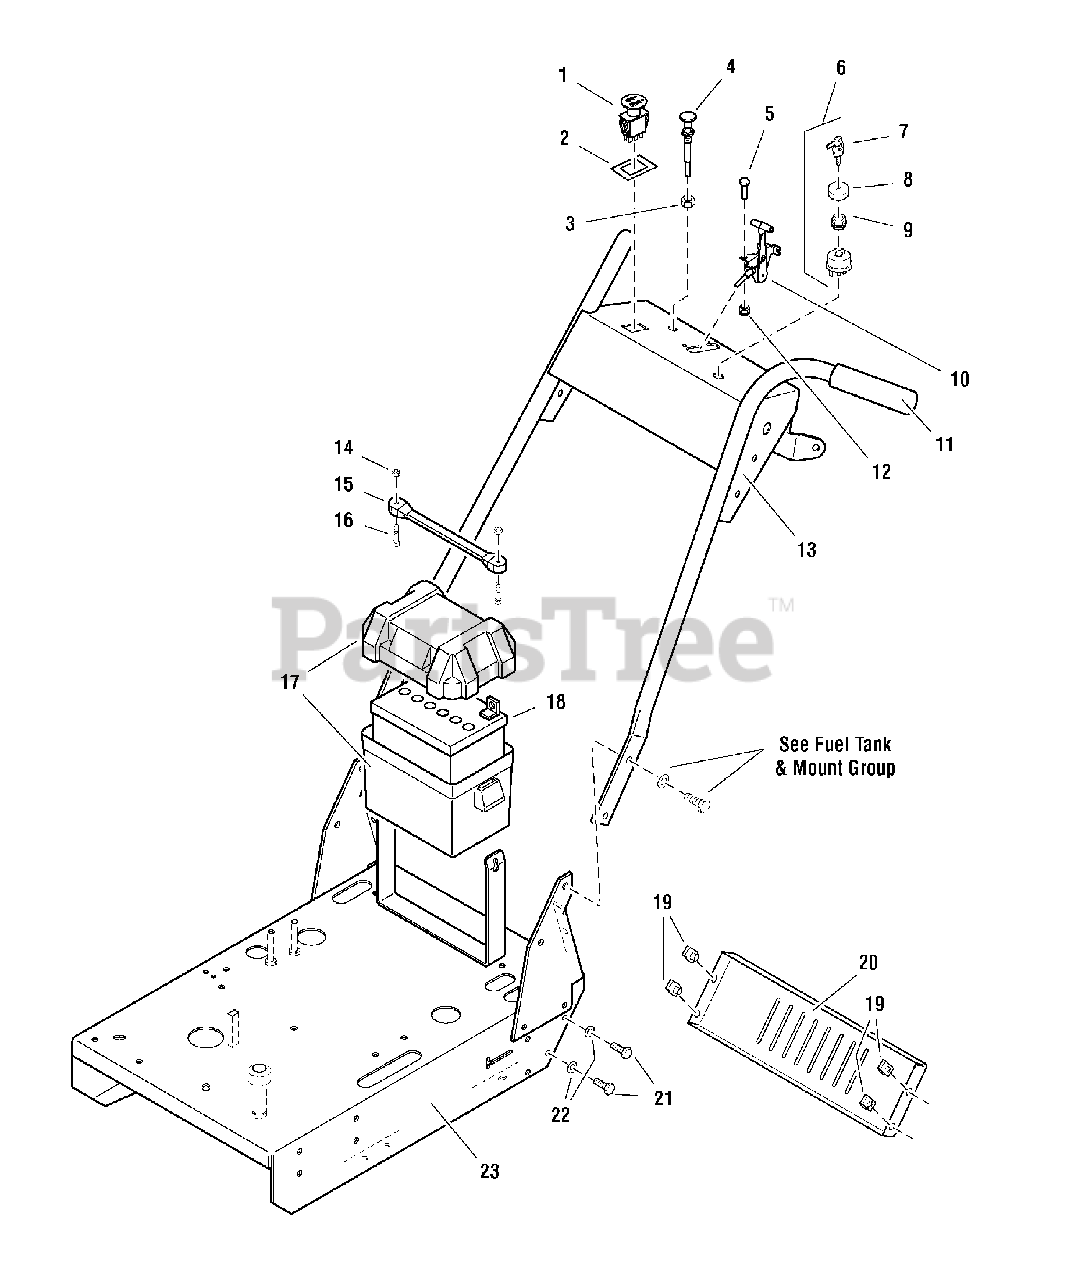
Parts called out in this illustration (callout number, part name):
1	SWITCH, PTO
2	SWITCH RETAINER RING
3	NUT, 3/8-24 Hex
4	CABLE, Choke Control, 47"
5	BOLT, 1/4-20 x 3/4
6	SWITCH, Ignition, Complete
7	KEY, Ignition, Molded Set
9	PLASTIC NUT
10	CABLE, Throttle Control, 46"
11	GRIP, Foam
12	NUT, 1/4-20 Hex Nylon Lock
13	HANDLE BAR ASSEMBLY
14	NUT, #10-24 Hex Nylon Lock
15	RUBBER STRAP
16	SCREW, #10-24 x 1
17	BATTERY BOX
18	BATTERY, Lawn & Garden, 12V (BCIU1, 340 CCA)
19	BODY CLIP, 5/16-18
20	REAR SHIELD
21	BOLT, 5/16-18 x 3/4
22	WASHER, 5/16" SAE
23	ENGINE DECK ASSEMBLY
